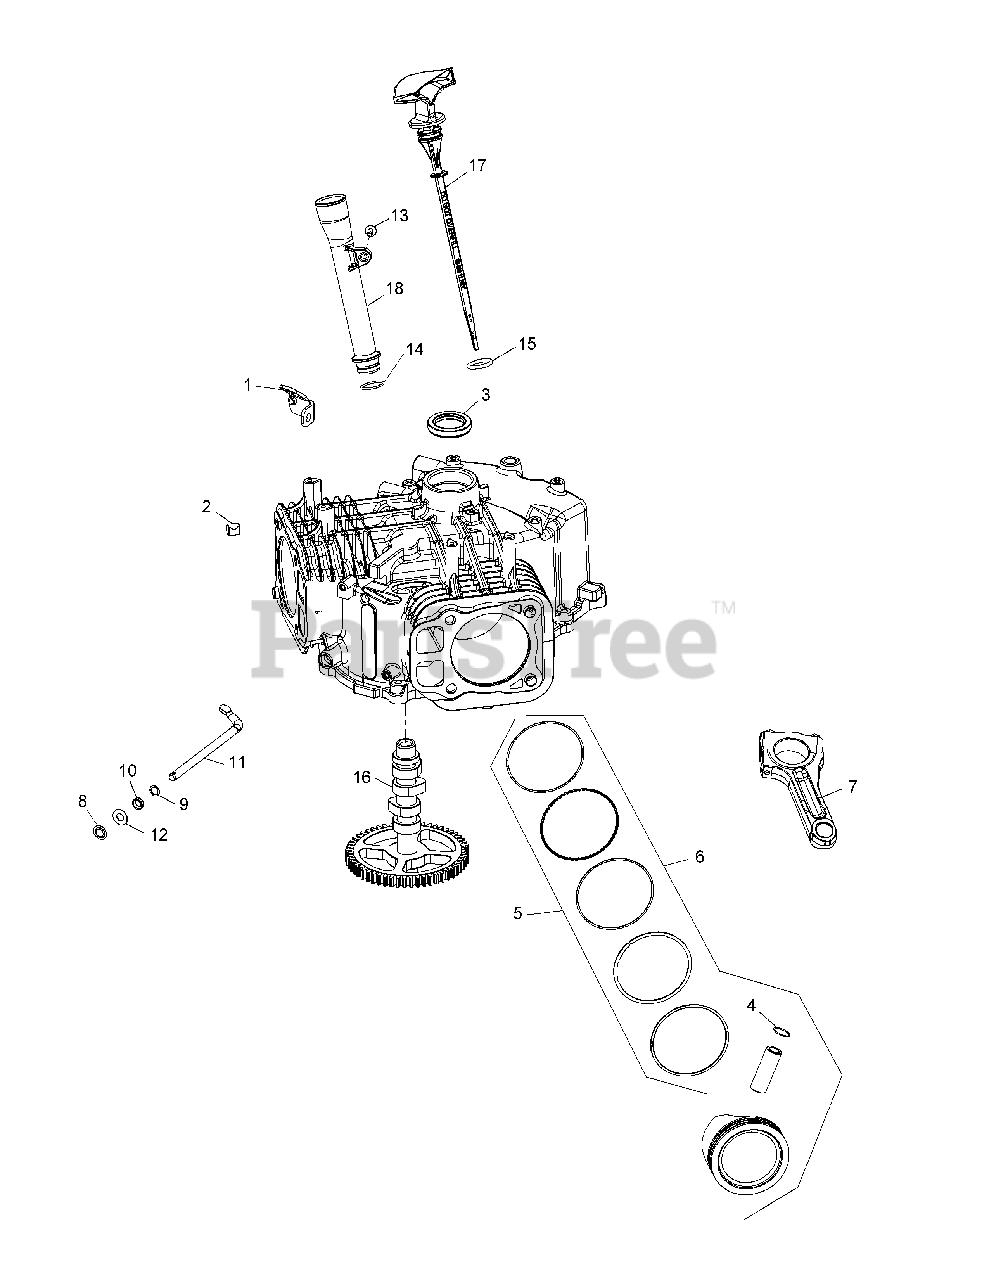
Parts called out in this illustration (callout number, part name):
3	Oil Seal, 1.78 x 1.26
4	Piston Pin Retainer
5	Piston Ring Set (STD)
5	Piston Ring Set (.08)
5	Piston Ring Set (.25)
5	Piston Ring Set (.50)
6	Piston Kit w/ Ring (STD) (Inc. 4 & 5)
6	Piston Kit w/ Ring (.08)
6	Piston Kit w/ Ring (.25)
6	Piston Kit w/ Ring (.50)
7	Connecting Rod (STD)
7	Connecting Rod (U/S .010) (25mm)
8	Ring Retainer
9	Flat Washer, 11/32"
10	Governor Cross Shaft Seal
11	Governor Cross Shaft
12	Flat Washer, 9 mm
13	Thread Forming Screw
16	Camshaft Assembly
17	Dipstick Assembly
18	Oil Fill Tube Assembly
